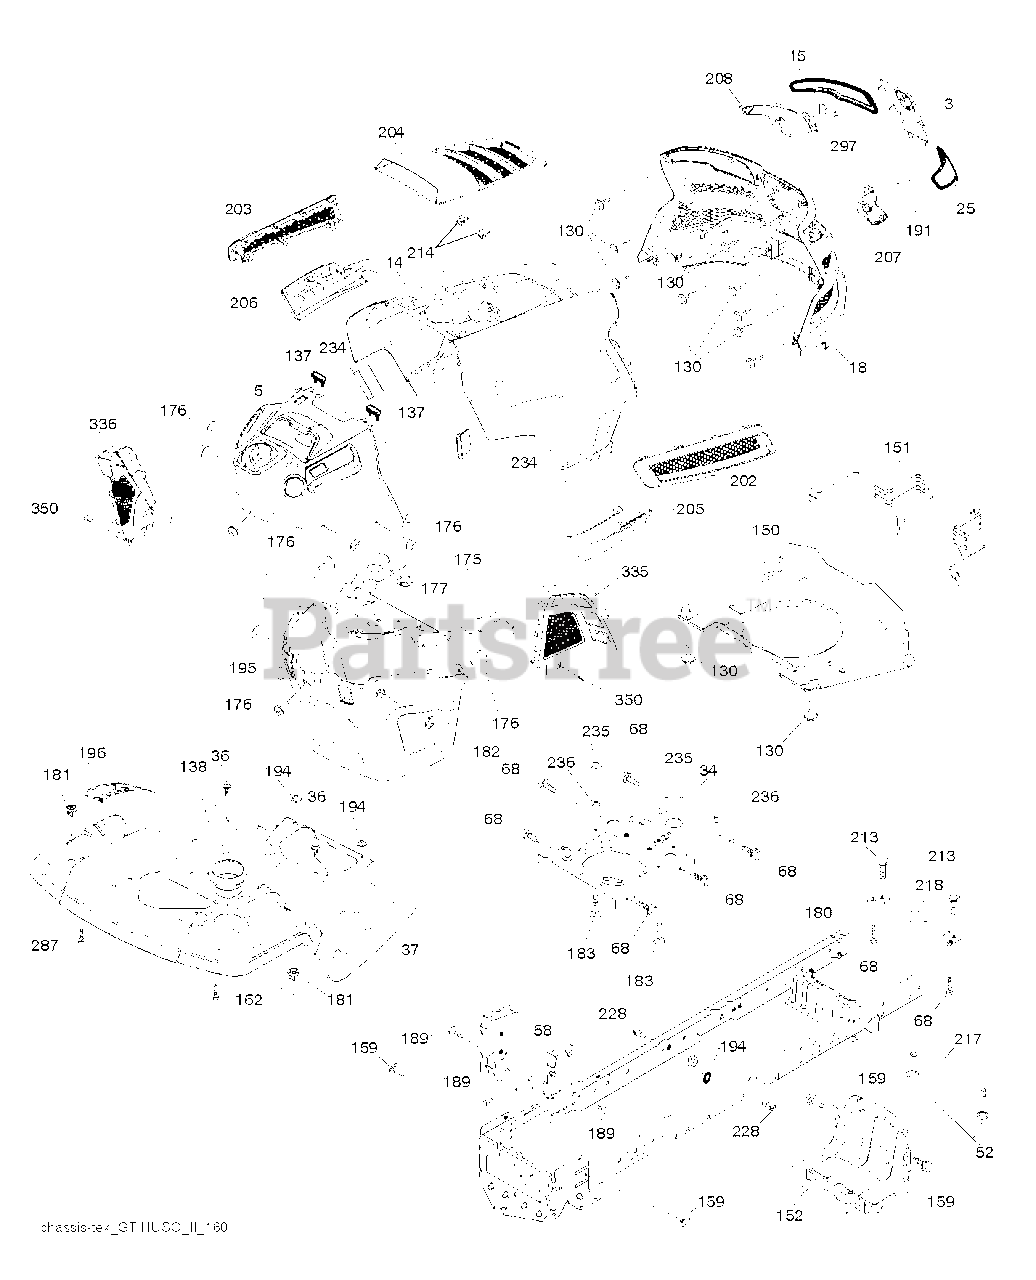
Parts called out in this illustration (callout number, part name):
3	APPLIQUE.SUBASM.GT.HUSQ.II
5	DASH.UPPER.ASSY.GT2.GREY
14	HOOD.ASM.HUSQVARNA.GT.TEX.ORAN
18	GRILLE.SUBSTRATE.2011.
25	LENS.HEADLIGHT.RH.GTII.2011
34	PLATE.ENGINE.WELDED.CHASSIS
36	SCREW 5/16"
37	FENDER.TLT.PDL.CNTRL.W/CPH.ORG
52	LOCKNUT
58	DRAWBAR UPPER 2PC SMALL FENDER
68	SCREW LT
130	SCREW.#10 X 0.750.BOS
137	BUMPER DASH
138	HOLDER.CUP.LT.GREY
150	AIR.DUCT.GTV.BLACK
151	BRACKET.PIVOT.HOOD.GT.HUSQ.II
152	SHIELD.BROWNING.PNT.GT.V2
159	SCREW, 3/8-16X3/4
162	SCREW.HI-LO.CONSOLE
175	PLATE.CROSSMEMBER.HUSQ
176	SCREW.#10-24X5/8.RN.QU
177	BUSHING, STEERING
180	CHASS.WLDMNT.TL.12GA/2P.48/54
181	BUSHING.MNT.FEND.CRGO.TEX.49
182	DASH.LOWER.COMMON.12V.ADAPTOR
183	BOLT.5/16-18X1-1/4 FULL THD
189	SCREW
191	INSERT.REFLECTIVE.RH.HUSQ.GTII
194	NUT LOCK HEX FLANGE 5/16-18
195	PLUG.HOLE.DASH.LOWER.12V.BLK
196	DECKLFT.CONSOL FULL ASSM GREY
202	VENT.SIDE.RH.GT.HUSQ.II.
203	VENT.SIDE.LH.GT.HUSQ.II.498
204	VENT.TOP.HUSQ.GT2
205	SIDE.TRIM.RH.GT.HUSQ.II
206	SIDE.TRIM.LH.GT.HUSQ.II.GRAY
207	BEZEL LIGHT.RH.GT.II.MYLAR
208	BEZEL LIGHT.LH.GT.II.MYLAR
213	BOLT
214	CLIP.RETAINER.TINNER.
217	ROD.PIVOT.HOOD
218	X-PIECE.HOOD.STOP.NON/
228	STUD.FASTNER.W/ANTI-ROTATE
234	BUMPER.HOOD.TEX.HUSQVARNA
235	SPACER FENDER
236	NUT.CENTERLOCK.5/16-
287	SCREW 1/4X20
297	INSERT.REFLECTIVE.LH.HUSQ.GTII
335	COVER.LOWER.DASH.RH.BLACK
336	COVER-LH.LOWER.DASH.GT2.BLACK
350	CLIP.X-MAS.TREE
